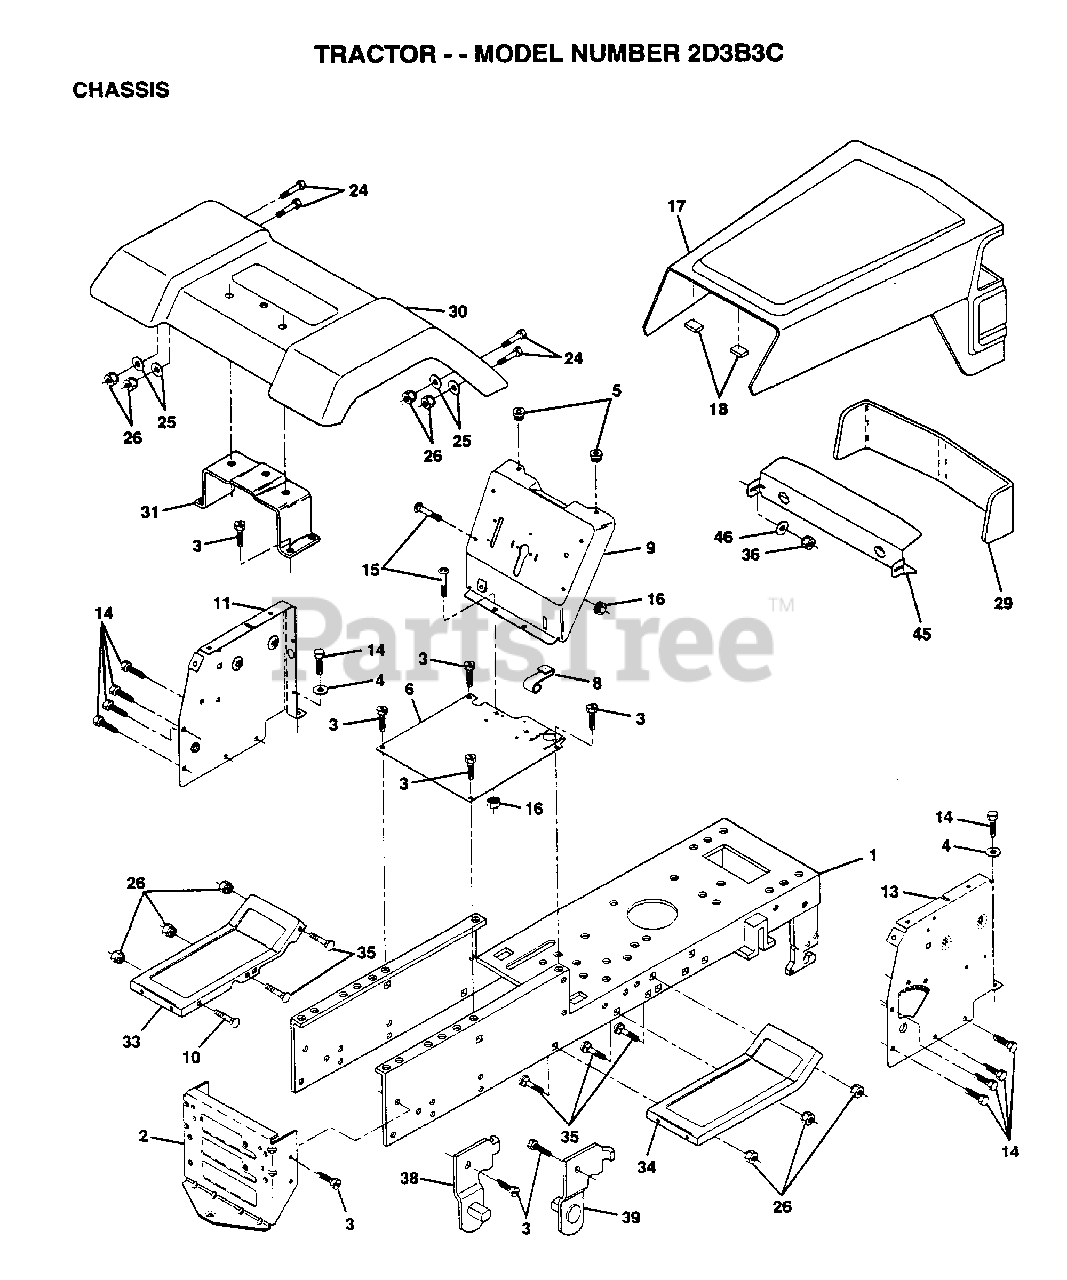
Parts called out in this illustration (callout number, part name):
1	CHASSIS.WLD.11GA
3	SCREW
4	WASHER
8	"CLIP,INSULATOR"
9	DASH.SLKSC.LT.1PC
11	DASH PANEL LH
14	SCREW LT
15	SCREW
17	HOOD/GRILL ASM
24	BOLT
25	WASHER
26	NUT
29	LENS SERVICE KIT
30	FENDER
31	BRKT FENDER
33	FOOTREST LH
34	FOOTREST RH
35	BOLT
36	PAL NUT LT
38	BRACKET ASM LH
39	BRACKET ASM RH
46	RETAINER
